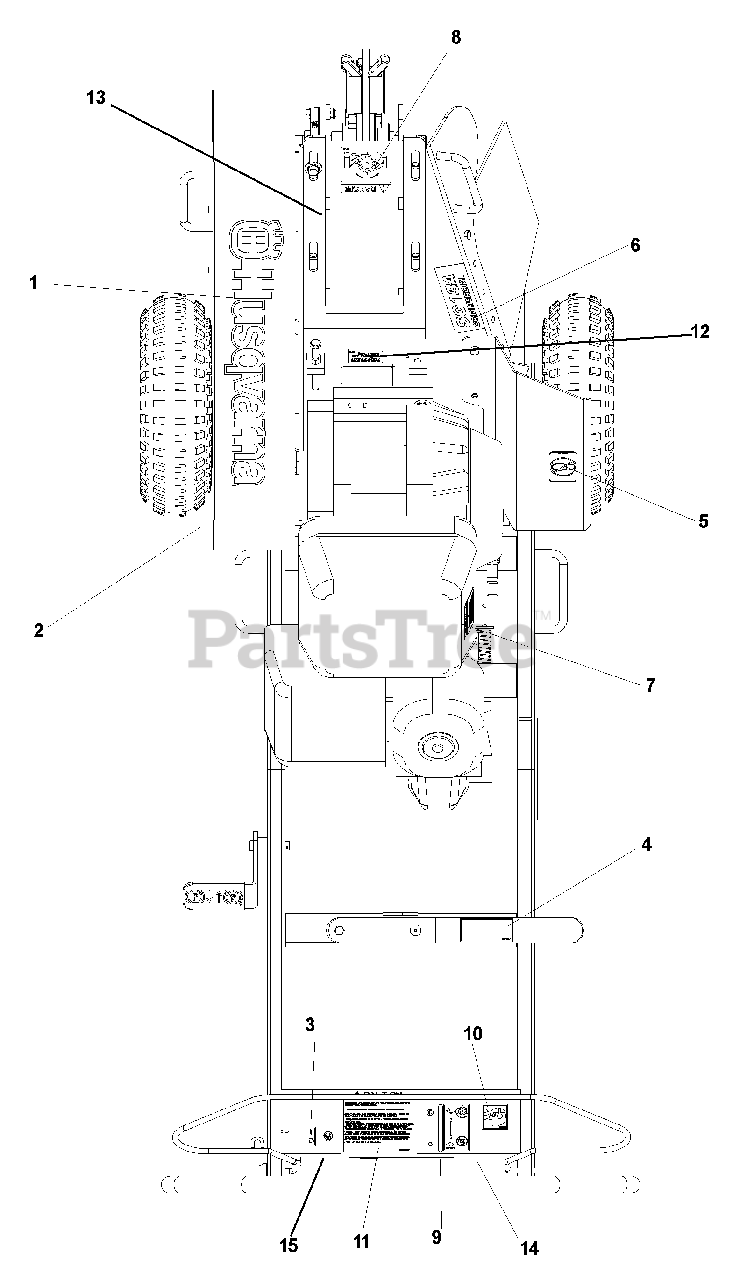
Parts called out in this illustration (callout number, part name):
1	DECAL, LOGO HUSQVARNA
2	DECAL, CROWN
3	DECAL, ON/OFF
4	DECAL, HANDLE ADJUSTMENT
5	DECAL, NO STEP
6	DECAL, SG13A STUMP GRINDER
7	DECAL, PROP 65
8	DECAL, DANGER FOOT
9	DECAL, THROTTLE
10	DECAL, EAR AND EYE WARNING
11	DECAL, CAUTION LIST
12	DECAL, CE968999239
13	DECAL, NASCAR
14	DECAL, 107DBA SOUND POWER
15	DECAL, OPN STUMP GRINDER
